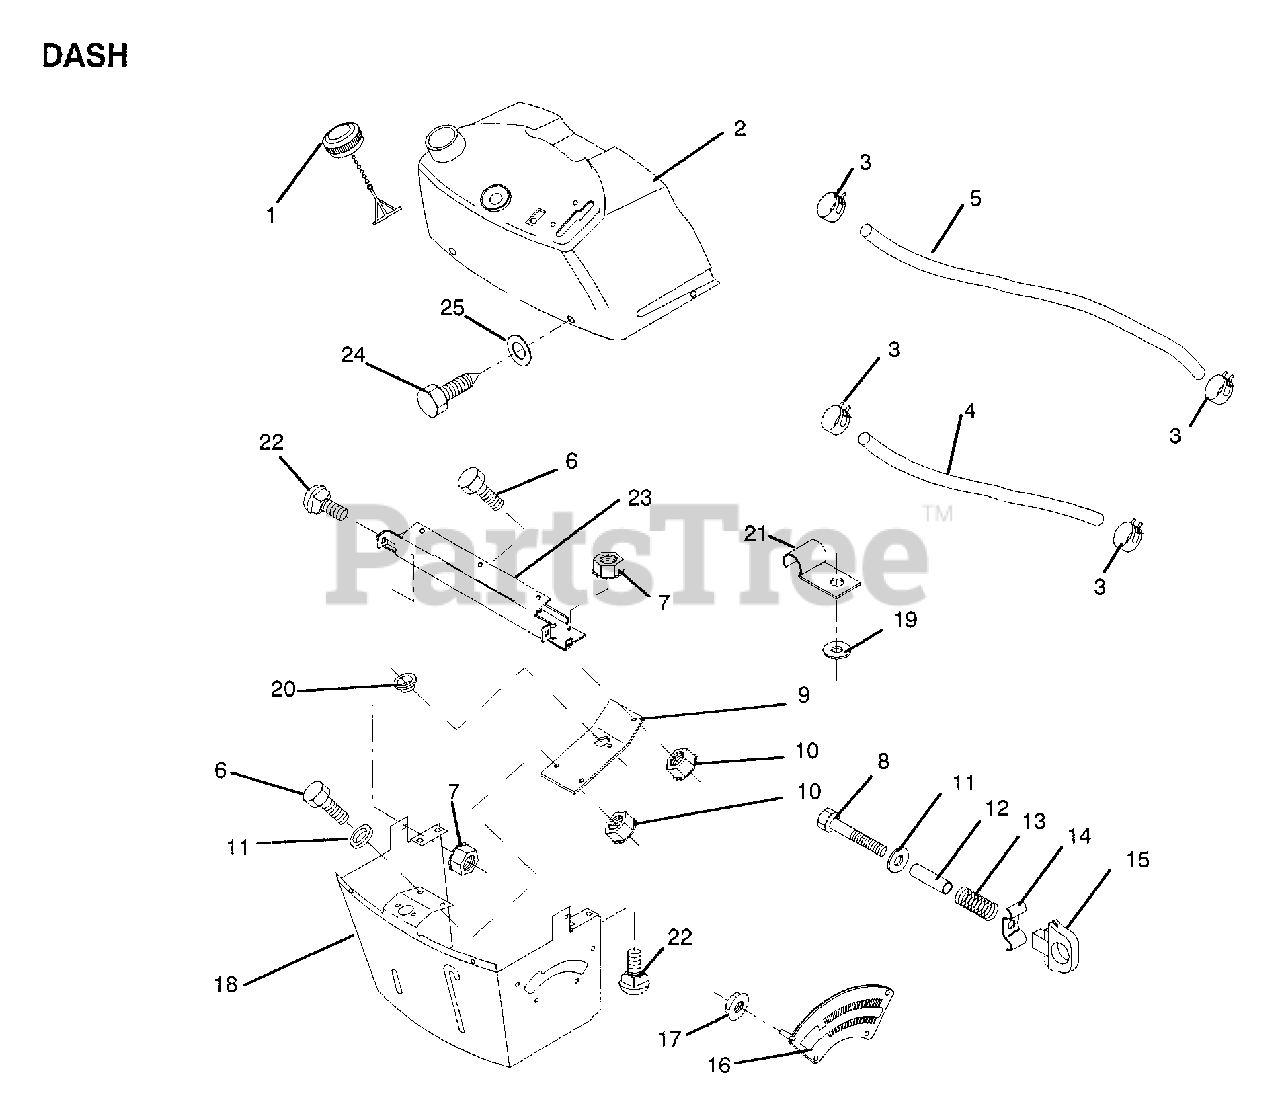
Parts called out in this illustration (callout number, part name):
3	HOSE CLAMP
4	FUEL LINE T
7	NUT
8	BOLT
10	LOCKNUT
11	WASHER
12	SPACER SPLIT
13	SPRING T
14	HEIGHT ADJ
15	KNOB
16	ADJUSTER QUAD
17	NUT
18	SUPPORT DASH
19	WASHER PM
21	CLIP T
22	BOLT
